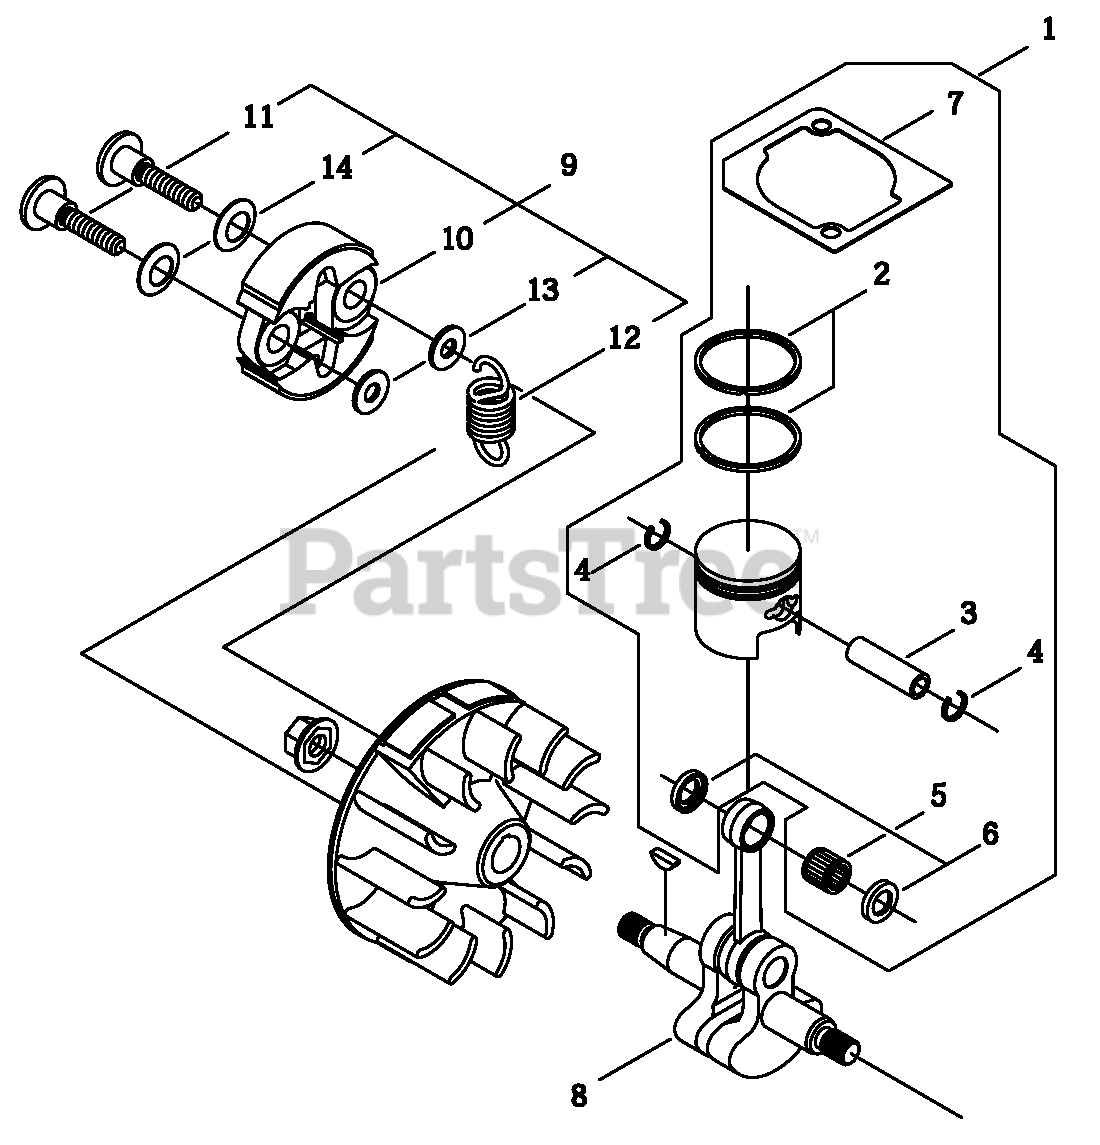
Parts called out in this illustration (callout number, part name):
1	PISTON KIT
2	RING, PISTON
3	PIN, PISTON 8
4	RING, SNAP
5	BEARING, NEEDLE 8
6	WASHER, THRUST 8
7	GASKET, CYLINDER
8	CRANKSHAFT
9	CLUTCH ASSY
10	SHOE, CLUTCH
11	BOLT, CLUTCH
12	SPRING, CLUTCH
13	WASHER 6 MM
14	WASHER, SPRING
